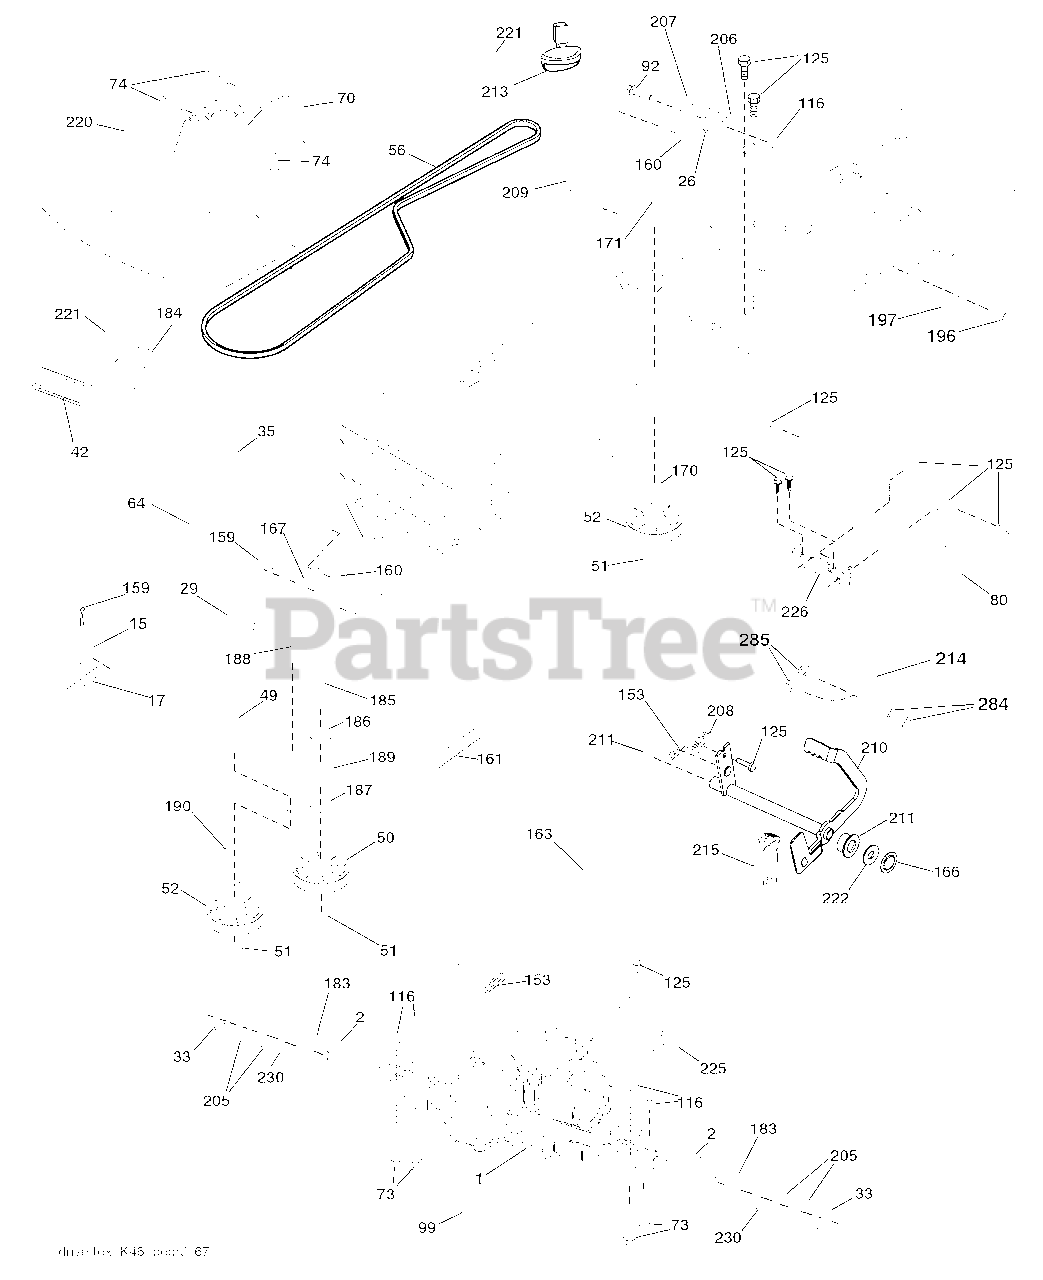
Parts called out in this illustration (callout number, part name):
1	Transaxle, TUFFTORQ K46 LD
15	Washer 13/32 x 13/16 x 16 Ga.
17	Spring, Brake
26	Spring Return Cruise
29	Rod, Brake
35	Rod, Brake, Park
42	Cover, Foot Pedal
50	Pulley Idler Flat
51	Lock Nut 3/8-16
52	Idler V-Groove 910" Offset
56	V-Belt, Drive
64	Shaft Asm. Pedal Brake Control
70	Console Asm
73	Bolt Hex Flghd 5/16-18 Gr. 5
74	Screw Hex Wsh Hi-Lo 1/4 x 1/2
80	Bracket Strap Torque
92	Bolt Fin Hex 5/16-18 unc x 1.25
99	Rod Spring Bypass
116	Nut Lock Hex Flange 5/16-18
125	Screw 5/16-18 x 3/4
153	Retainer Spring
159	Pin Cotter 1/8 x 3/4
160	Retainer Clip
161	Spring, Return, Clutch
163	Rod Pedal Control
167	Latch Brake Parking
170	Keeper Belt Centerspan
171	Bolt RDHD SQNK 3/8-16 unc x 2
183	Spacer Split
184	Handle Parking Brake
185	Bolt Rdhd Sqnk 3/8-16 x 2-3/4 Gr. 5
186	Spacer Retainer
187	Washer
188	Link Clutch Ground Drive
189	Bellcrank Ground Drive
190	Keeper Bellcrank Ground Drive
196	Screw 3/8-16 x 1
197	Bracket Clutch Anti-Rotation
206	Bracket Mount Latch Cruise
207	Latch Control Cruise
208	Gear Sector Control Cruise
209	Rod Control Cruise
210	Rocker Asm. Pedal Control
211	Bearing Nylon
213	Knob Control Cruise
214	Pedal Forward
215	Pedal Reverse
220	Reflector RH
221	Retainer Spring Clip Handle
222	Washer 21/32 x 1-1/4 x 10 Ga.
225	Keeper Belt Trans.
226	Bracket Mount Touque
230	Washer Hardened
284	Nut U CHNL 1/4-20
285	Screw PHD 1/4-20
